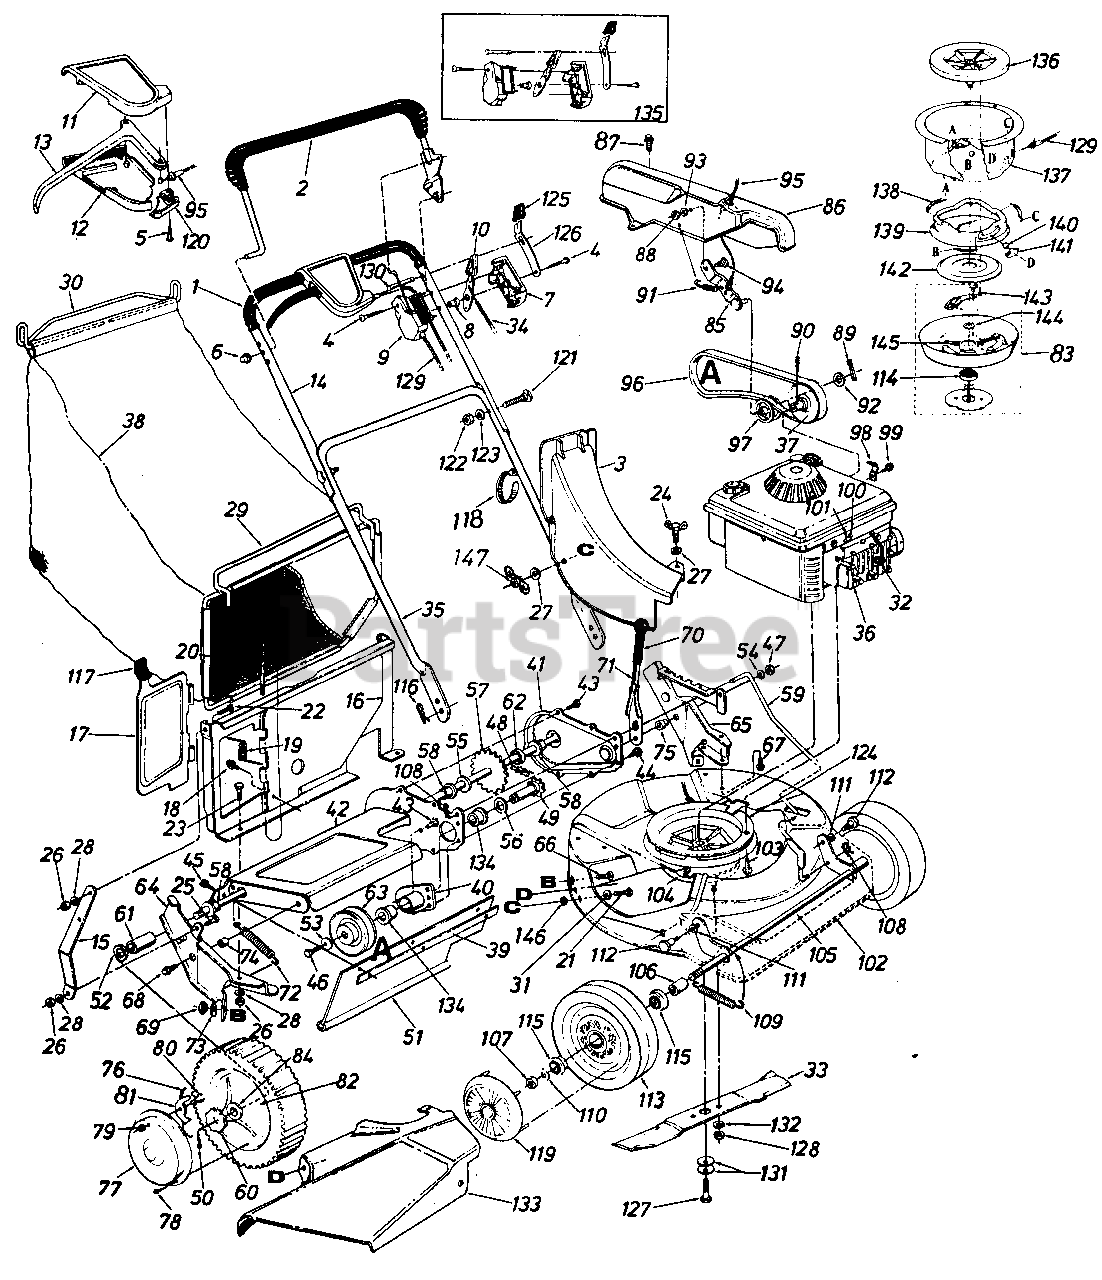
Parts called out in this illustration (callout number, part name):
2	Control Handle Ass'y.-L.H.
3	Top Discharge Chute Ass'y.
4	Truss Mach. Scr. #12 x 1.50" Lg.
5	Fl-"C"-Sunk Hd. Tap Scr. #10 x .75" Lg.
6	Cap Speed Nut .31 Dia.
7	Control Panel Half
8	Control Disc Pin
9	Clutch Panel Half
10	Throttle Control Lever
11	Self-Propelled Control Cover
12	Self-Propelled Control Cover
13	Control Lever
14	Upper Handle-Chrome
15	Panel Support Brkt.
16	Top Catcher Panel
17	Top Door
18	Hex "B" Tap Scr. #10 x .38" Lg.
19	Torsion Spring .20" I.D. x 1.14" Lg.
20	Pivot Pin .187" Dia. x 7.25" Lg.
21	Carriage Bolt 1/4-20 x .62"
22	Truss Mach. Scr. 1/4 x .50" Lg.
23	Hex Bolt 1/4-20 x .50" Lg.
24	Wing Bolt 1/4-20 x .62" Lg.
25	Hex Bolt 1/4-20 x .62" Lg.
26	Hex Nut 1/4 -20 Thd.
27	Fl-Wash. .280" I.D. x .620" O.D.
28	L-Wash. 1/4" I.D.
29	Front Grass Catcher Frame
30	Grass Catcher Handle
31	Fl-Wash. .344 I.D. x .62 O.D.
32	Spark Plug Insulator
33	21" Blade
34	Throttle Control Wire 58.0" Lg.
35	Lower Handle-Chrome
36	Engine
37	Engine Pulley 1/2"
38	21" Top Discharge Grass Bag
39	Retaining Strip
40	Bearing Hub Flange Ass'y.
41	Chain Cover
42	Chain Axle Ass'y.
43	Hex B-Tap Scr. 1/4" x .38"
44	Hex Wash. S-Tap Scr. 1/4-20 x.50" Lg.
45	Hex AB-Tap Scr. 1/4 x .62" Lg.
46	Hex Wash. TT-Tap Scr. 1/4-20
47	Hex Patch L-Nut 3/8-24 Thd.
48	#48 Chain .500" Pitch x .30 Links
49	Sprocket-Shaft Ass'y.
50	Cotter Pin 1/8" Dia. x 1.00" Lg. *
51	Rear Flap 3.75" x 17.30" Lg.
52	Fl-Wash. .531" I.D. x .930" O.D.
53	Bell-Wash. .265" I.D. x .75"O.D.
54	Fl-Wash. .385" I.D. x .87"
55	Fl-Wash. .510" I.D. x 1.0"
56	Fl-Wash. .62" I.D. x 1.12" O.D.
57	Rear Shaft Ass'y. 22.05" Lg.
58	Hex Flange Bearing .506" I.D. Plastic
59	Height Adj. Rod 1.50" x 19.42" Lg.
60	Ratchet Wheel 1.62" O.D.
61	Spacer. 51" I.D. x .69" O.D. x.690" Lg.
62	Spacer. 510" I.D. x 1.00" O.D. x .210" Lg.
63	1/2""V"-Pulley
64	R.H. Handle Wheel Brkt. Ass'y.
65	L.H. Handle Wheel Brkt. Ass'y.
66	Carriage Bolt 5/16-18 x .62" Lg.
67	Hex Wash. Hd. B-Tap Scr. 511 6-1 8
68	Hex Wash. Hd. TT-Tap Scr. 3/8-1 6
69	Hex Nut 5/16-18 Thd.
71	Height Adj. Lever 1.25 x 8.5" Lg.
72	Extension Spring .50" O.D. x 3.80" Lg.
73	Bell-Wash. .345" I.D. x .88"
74	Spacer.385" I.D. x .502n O.D. x .270" Lg.
75	Shld. Spacer. 500" Dia. x .100
76	Spring-Nylon
77	Hub Cap
78	Pan Hd. Tap Scr. #12 x .50"
79	Hex Ins. L-Nut 1/4-20 Thd.
80	Shld. Scr. .342" Dia. x .268
81	Pawl
82	Wheel Ass'y. Comp.-Rear 8 x 1.75
83	Clutch Blade Housing Ass'y.
84	Flange Ball Bearing 1/2" I.D.
85	Belt Idler Bracket Ass'y.
86	Belt Cover
87	Hex Wash. S-Tap Scr. 1/4-20 x.50" Lg.
88	Hex Nut 1/4 -20 Thd.
89	Cotter Pin 1/8" Dia. x 1.00" Lg.
90	Spring Pin Spir. 3/16" Dia. x 1.00" Lg.
91	Extension Spring .33" O.D. x 1.12" Lg.
92	Fl-Wash. .531" I.D. x .930" O.D. x .050
93	L-Wash. 1/4" I.D.
94	Shld. Bolt .375" Dia. x .181
95	S.P. Cable x 53.0" Lg.
96	"V"-Belt 1/2" x 32.0" Lg.
97	Fl-Idler Plastic 1.62" Dia.
98	Throttle Control Cable Clip
99	Hex B-Tap Scr. #10 x .38" Lg.
100	Hex Sems Bolt #10-32 x .62" Lg.
101	Casing Clamp
104	Speed Nut 1/4-20 U-Type
105	Front Axle Ass'y.
106	Sleeve .526" I.D. x .690" O.D. x .880" Lg.
107	Hex L-Nut 1/2-2 Thd.
108	Intern. Cotter Pin 5/16" Dia.
109	Extension Spring .50" O.D. x 3.20" Lg.
110	Fl-Wash. .531" I.D. x .930" O.D.
111	Intern. L-Wash. 3/8 x .56" O.D.
112	Shld. Bolt .623" Dia. x .425
113	Front-Wheel Ass'y. Comp. 7 x 1.75
114	Ball Brg. .669" I.D. x 1.574"
115	Flange Ball Bearing 1/2" I.D.
116	Intern. Cotter Pin 5/16" Dia.
117	Door Grip x 2.5
118	Cable Tie
119	Hub Cap-Plastic
120	S.P. Control Cover
121	Curved Carr. Bolt 5/16-18 x 1.38" Lg.
122	Hex Nut 5/16-18 Thd.
123	L-Wash. 5/16" I.D.
124	Blade Brake Clutch Comp.
125	Spring Lever Knob
126	Lockout Spring
127	Hex Cent. L-Bolt 3/8-24 x 2.00" (Grade 8)
128	Hex Nut 3/8-24 Thd. (Grade 8)
129	BBC Clutch Cable x 46.0" Lg.
130	Lock Pin .314" Dia. x 1.75" Lg.
131	Bell-Wash. .400" I.D. x .88" O.D.
132	L-Wash. 3/8" I.D.
133	Side Chute Deflector
134	Flange Bushing
135	Kit-Control Housing Comp.
136	Fan Adapter
137	Clutch Housing
138	Extension Spring .35" O.D. x 1.75" Lg.
139	Brake Cup Cone
140	Steel Ball .500" Dia.
141	Ball Block
142	Clutching Cone
143	Hex Tap L-Scr. 1/4-20 x .75"
144	Fl-Wash. .690" I.D. x 1.060" O.D.
145	Compression Spring .35" O.D. x 2.00" Lg.
146	Bolt Retainer 1/4 x .50 O.D.
147	Wing Nut
